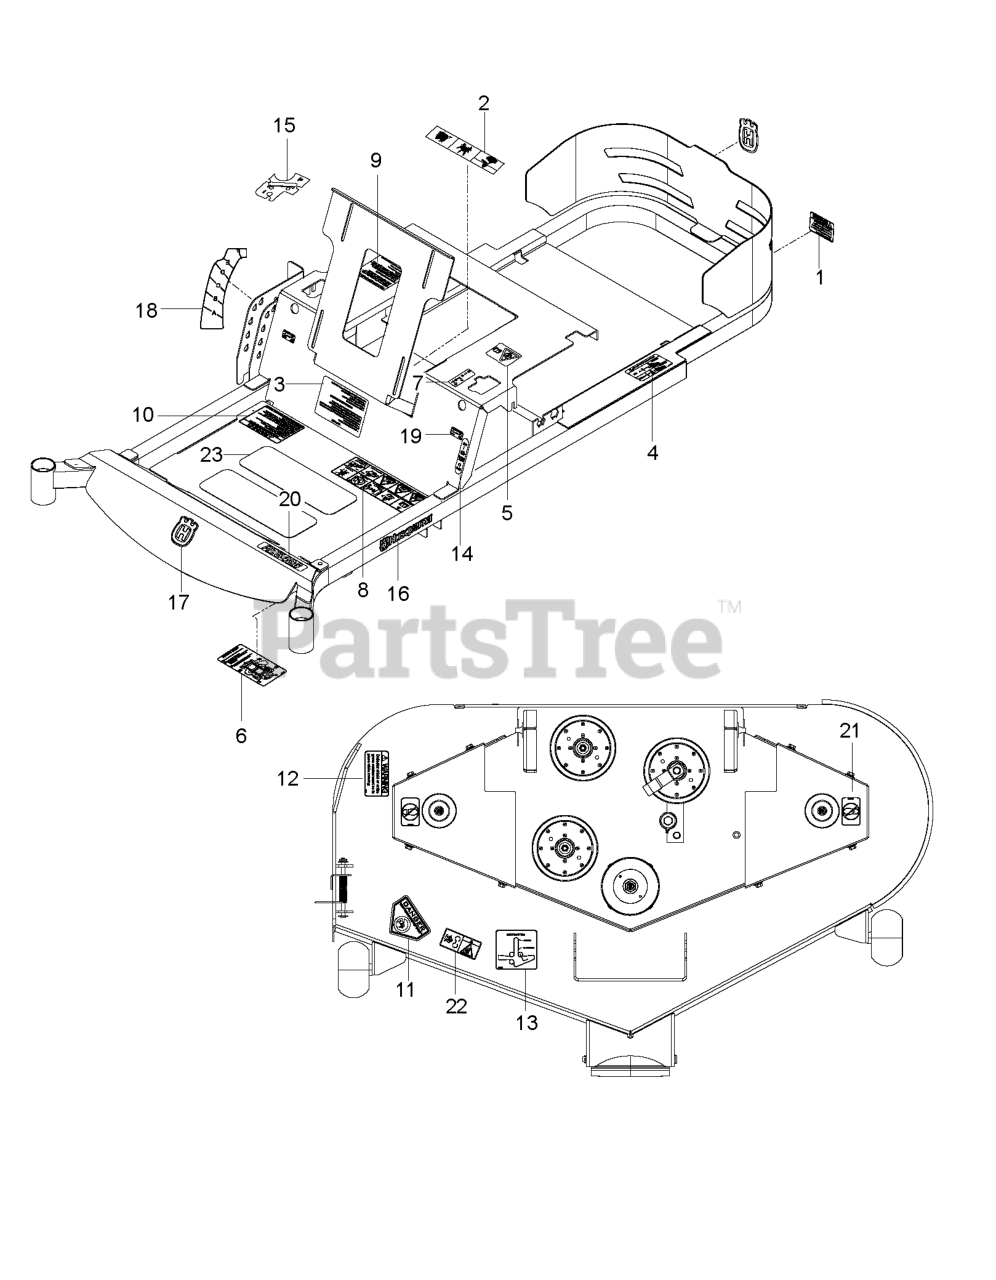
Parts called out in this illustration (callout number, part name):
1	DECAL, PROP. 65
2	EURO DECAL-BATTERY WARNIN6
3	DECAL, START
4	DECAL, DO NOT TOW
5	DECAL, EXITING MOWER
6	DECAL, SERVICE
7	DECAL, MOTION CONTROL
8	DECAL, SAFETY WARNING
9	DECAL, CUSTOMER RESPNSIBILITY
10	DECAL, WARNING
11	DECAL, CPSC
12	DECAL, CAUTION
13	DECAL, BELT ROUTING
14	DECAL, PARK BRAKE
15	DECAL, CTRL PANEL, HUSQ
16	RP.DECAL.BADGE.170MM.TEXTLOGO
17	DECAL.AUGER.HUSQ.CROWN.SNOW
18	DECAL, HEIGHT
19	DECAL, F.S.T.
20	DECAL, EZ4824
21	DECAL, NO STEP
22	DECAL, EURO SEVERING
23	ANTI-SKID PAD
